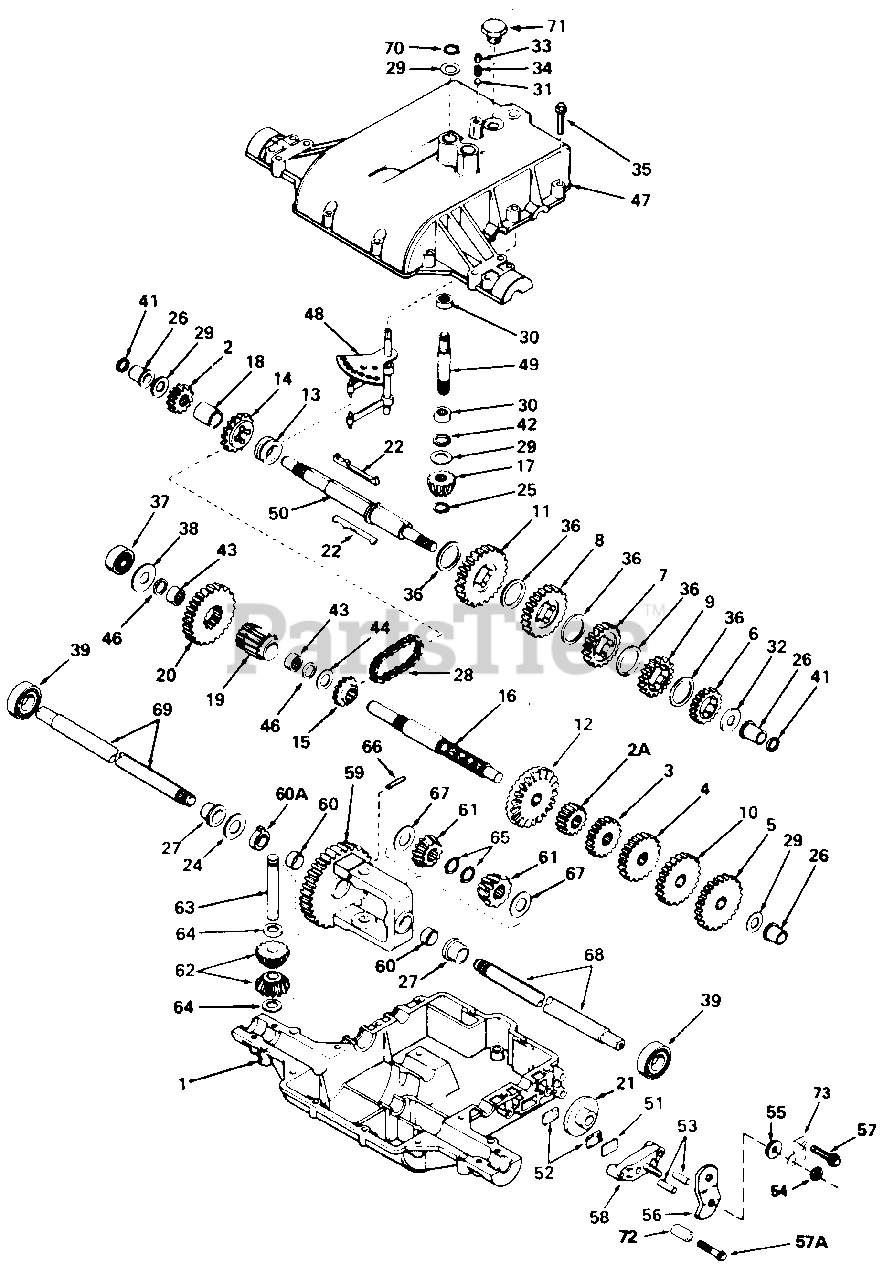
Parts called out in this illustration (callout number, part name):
1	Case: Transaxle
2	Gear: Spur (15 teeth)
2A	Gear: Spur (12 teeth)
3	Gear: Spur (20 teeth)
4	Gear: Spur (25 teeth)
5	Gear: Spur (30 teeth)
6	Gear: Spur (20 teeth)
7	Gear: Spur (25 teeth)
8	Gear: Spur (30 teeth)
9	Gear: Spur (22 teeth)
10	Gear: Spur (28 teeth)
11	Gear: Spur (37 teeth)
12	Gear: Bevel (42 teeth)
13	Collar: Shift
14	Sprocket (18 teeth)
15	Sprocket (9 teeth)
16	Shaft: Counter
17	Bevel Pinion: Input
18	Spacer
19	Pinion: Output
20	Gear: Output
21	Disk: Brake
22	Key
24	Washer
25	Ring: Retaining
26	Bushing: Flanged
27	Bushing: Flanged
28	Chain: Roller (No. 41 Chain: 24 Links)
29	Washer: Thrust
30	Bearing: Needle
31	Ball: Steel
32	Washer: Thrust
33	Screw: Set: 3/8-16 x 3/8
34	Spring
35	Screw: Hex Hd. Thread Forming: 1/4-20 x 11/4
36	Washer: Thrust
37	Bearing: Ball
38	Washer: Flat
39	Bearing: Ball
41	Ring: Square Cut
42	Ring: Square Cut
43	Bearing: Needle
44	Washer: Flat
46	Ring: Square Cut
47	Cover: Transaxle
48	Rod & Fork Ass'y.: Shift
49	Shaft: Input
50	Shaft: Brake
51	Plate: Brake Pad
52	Pad: Brake
53	Pin: Dowel
54	Locknut: 5/16-24
55	Washer: Flat
56	Lever: Brake
57	Screw: Hex Hd. Thread Forming: 1/4-20 x 11/4
57A	Screw: Hex Hd. Thread Forming: 1/4-20 x 21/4
58	Holder: Brake Pad
59	Gear Ass'y.: Differential
60	Bushing
60A	Bushing
61	Gear: Bevel
62	Pinion: Bevel
63	Pin: Drive
64	Washer: Thrust
65	Ring: Retaining
66	Pin: Roll
67	Washer: Thrust
68	Axle (15-1/4" Long)
69	Axle (13-3/8" Long)
70	Ring: Retaining
71	Plug: Hex Hd.: 9/16-18 Thread
72	Spacer
73	Bracket: Brake Lever
